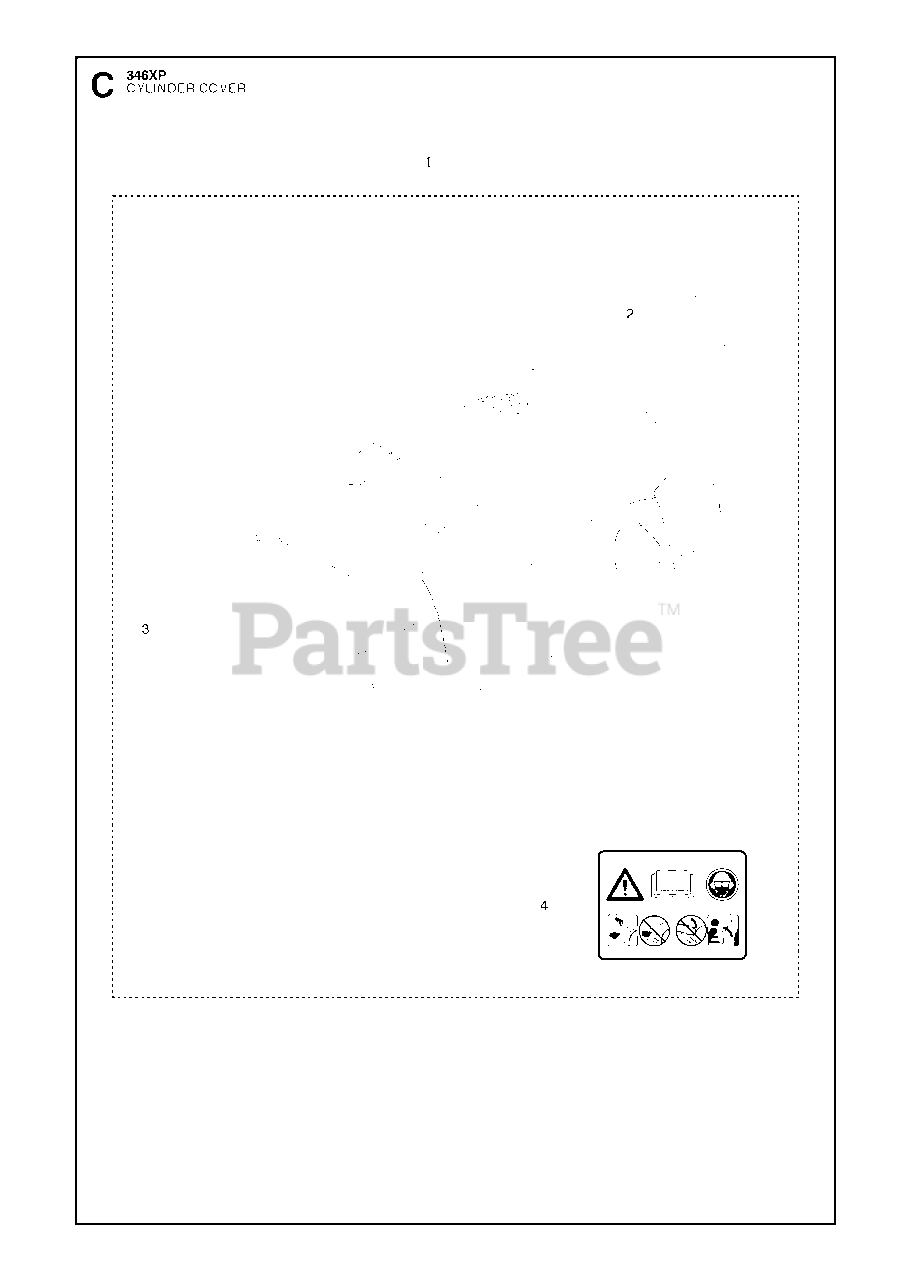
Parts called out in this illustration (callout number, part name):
1	CYLINDER COVER ASSY
2	COVER
3	INSULATING FOIL/CYLINDER COVER
4	DECAL
